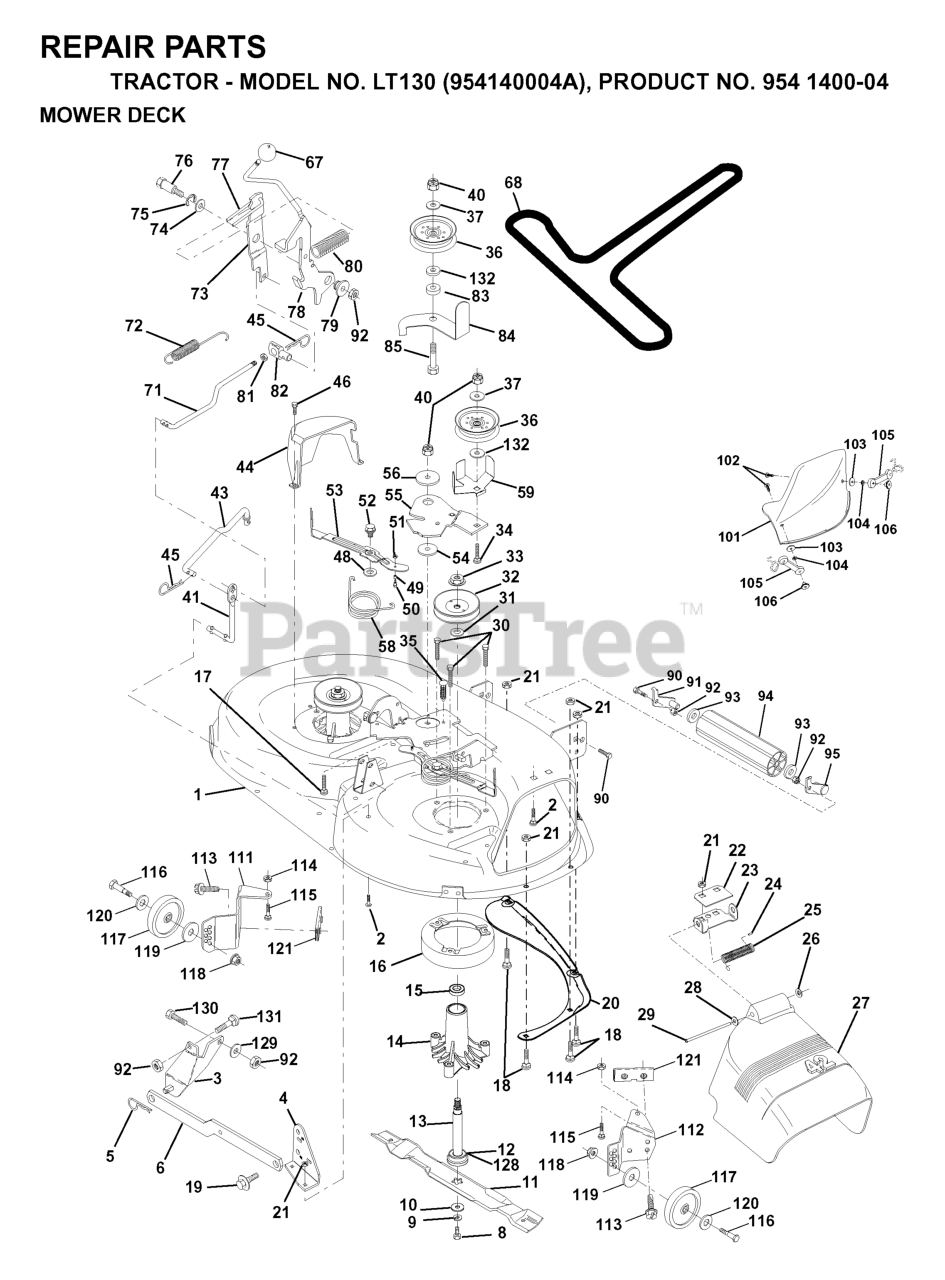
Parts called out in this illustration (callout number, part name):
1	DECK 42"
2	RP BOLT 5/16-18 X3/4 ZN/YEL GR
3	BRKT ASM SWAY BAR
4	BRKT DECK SW BAR
5	RETAINER-SPRNG RB
6	REAR SUSP ARM
8	BLADE BOLT
9	LOCKWASHER
10	WASHER.BLADE
11	BLADE.42".MULCH
12	BEARING.BALL.#6204.(MANDREL)
13	SHAFT ASM VENT
14	HOUSING.MANDREL.VENTED (MACHD)
16	STRIPPER
17	BOLT
18	BOLT
19	BOLT SHD 5/16-18
20	BAFFLE
21	LOCKNUT
22	STIFFENER BRACKET
23	DEFLECTOR BRACKET
24	CAP-SLEEVE LT
25	SPRING TORSION
26	NUT PUSH M
27	SHIELD.DEFLECTOR.MOWER.42".BLK
28	Washer 11/32 x 5/8 x 16 Ga SD
29	ROD.HINGE
30	SCREW
31	WASHER
32	PULLEY/MANDREL
33	NUT
35	FASTENER.XMAS.TREE
36	FLAT IDLER PULLEY
37	WASHER
43	CLUTCH ROD
44	GUARD MANDREL LH BLACK
45	RETAINER M
46	SCREW.1/4-20X5/8
49	ROLLER ASSY
52	BOLT.SHOULDER.5/16-18
53	ARM ASM PAD BRAD
54	HARDENED WASHER
55	ARM IDLER 42" MOWER LT/YT
56	SPACER RETAINER
59	GUARD, BELT
67	KNOB T (1/2-HOLE)
68	V-BELT TRIPATH
71	CLUTCH ROD
72	RETURN SPRING
73	ARM CLUTCH SECONDARY
77	KEEPER SPRING
78	ARM ASM CLUTCH PRIMARY
79	BUSHING.FLANGE.E-RING.GROOVE
80	SPRING-CLUTCH (2 2 PW01)
81	NUT
82	TRUNNION.ADJUSTABLE.3/8-16
84	KEEPER BELT
85	BOLT
90	BOLT
91	BRACKET LH (A)
92	NUT
93	Washer 1 17/32 X 7/8 X 16 Ga
94	NOSE ROLLER
95	BRACKET RH (B)
101	COVER MULCH 42"
102	SCREW
104	LOCKWASHER #10
105	LATCH ASSEMBLY
106	WELDNUT
111	BRACKET WHEEL GAUGE LH 42" DK
112	BRACKET WHEEL GAUGE RH 42" DK
113	SCREW.THDROL.5/16-18X3/4.TTY
114	NUT
115	BOLT.CARR.5/16-18X1/2
116	BOLT M
117	WHEEL.GAUGE.BLK.4.93
118	LOCKNUT
119	WASHER.5/16.FLAT.STE.STD.
120	Washer 17/32 x 15/16 x 12 Gauge
121	BRACKET.EXTRUDED.GAGE.WHEEL
128	WASHER FELT
129	WASHER
131	BOLT D
